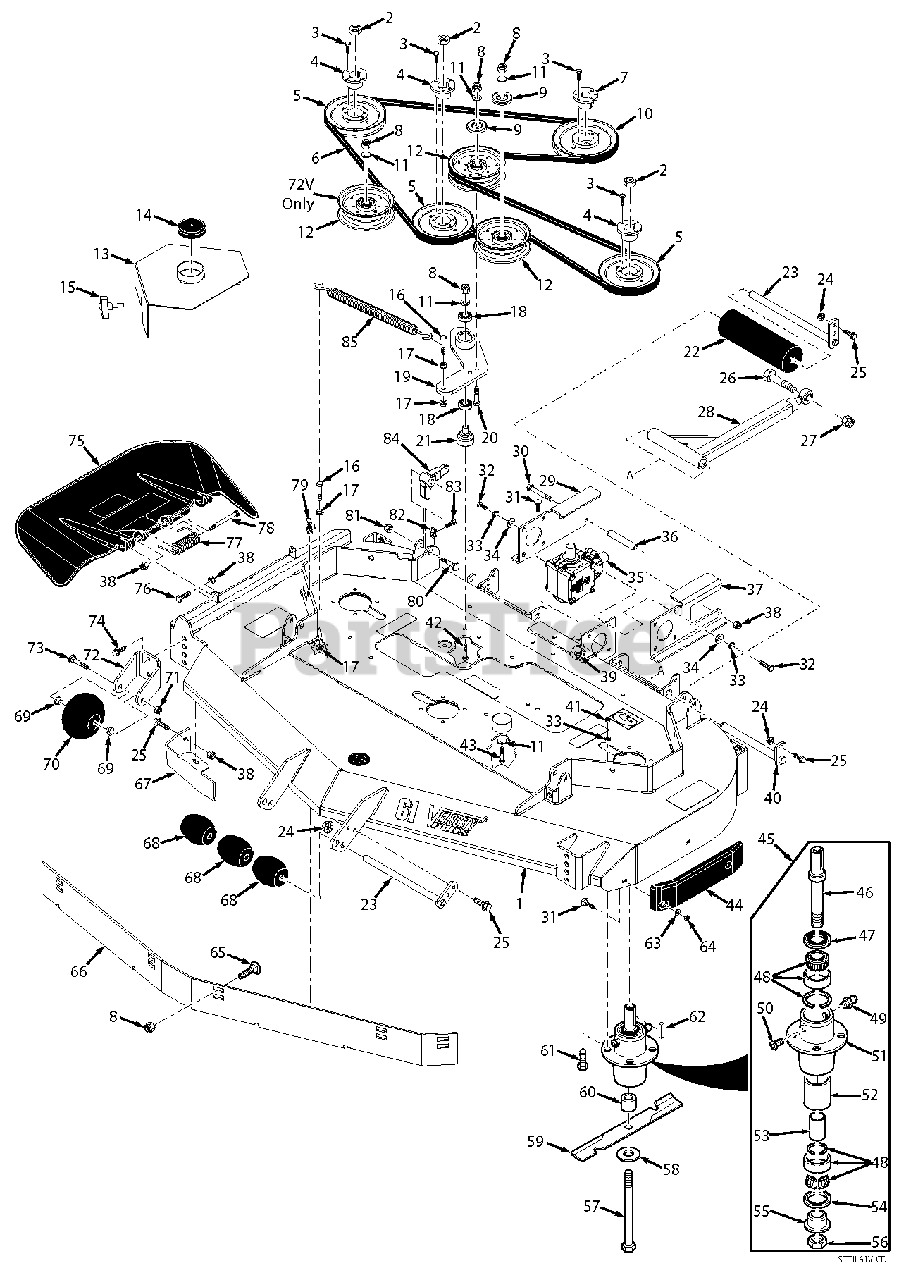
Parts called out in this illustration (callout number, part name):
1	Cutter Deck w/Decals - 72V
2	Nut, 5/8-11 UNC
3	Bolt, Hex Head 1/4-20 x 1"
4	Tapered Hub, 1-1/8" Bore
5	Pulley, 6.35 O.D.
5	Pulley, 6.95 O.D.
6	Belt, Deck Drive - 72V
7	Tapered Hub, 1" Bore
8	Nut, Elastic Stop 3/8-16
9	Dust Shield
10	Pulley, 6.75 O.D.
10	Pulley, 6.35 O.D.
10	Pulley, 5.75 O.D. (72V-25KBD)
11	Flatwasher, 3/8-.391 x .938 x .105 HD
12	Pulley, Idler
13	Belt Cover, LH 72V
13	Belt Cover, RH 72V
14	Cap, Spindle
15	Knob w/Stud
16	Bolt, Hex Head 3/8-16 x 1-1/2"
17	Nut, Serrated Flange 3/8-16
18	Bearing
19	Idler Arm Assy.
20	Bolt, Hex Head 3/8-16 x 2-3/4"
21	Pivot, Idler
22	Guide Roller
23	Roller Shaft
24	Nut, Serr. Flange 5/16-18
25	Bolt, Hex Head 5/16-18 x 1"
26	Bolt, Hex Head 5/8-11 x 4-1/2"
27	Nut, Elastic Stop 5/8-11
28	Pusharm Assy., LH & RH
29	Mounting Plate
30	Bolt, Hex Head 5/16-18 x 4-3/4"
31	Bolt, Carriage 5/16-18 x 3/4"
32	Bolt, Hex Head 5/16-18 x 1"
33	Lockwasher, 5/16"
34	Flatwasher, 5/16-.375 x .875 x .083
35	Gearbox
36	Spacer
37	Mounting Plate
38	Nut, Elastic Stop 5/16-18
39	Nut, Serr. Flange 5/16-18
40	Shaft Weldment, Pusharm
41	Nut, Elastic Stop 5/16-18
42	Bolt, Hex Head 3/8-16 x 3"
43	Bolt, Hex Head 3/8-16 x 3-3/4"
44	Pad, Deck Wear
45	Spindle Assembly
46	Shaft, Spindle
47	Seal, Top
48	Bearing Assembly
49	Grease Fitting
50	Relief Fitting, Tapered Spindle
51	Spindle Housing
52	Spacer, Outside
53	Spacer, Inside
54	Seal, Bottom
55	Spindle Bushing, Bottom
56	Nut, Special 1-1/16 - 18
57	Bolt, Hex Head 5/8-11 x 9-1/2
58	Flatwasher, 5/8-.688 x 1.75 x .134 HD
59	Cutter Blade, 24-1/2"
60	Spacer, Spindle Bottom
61	Bolt, Hex Head 5/16-18 x 1-3/4"
62	Key, 1/4 x 1/4 x 2"
63	Flatwasher, 5/16-.344 x .688 x .065
64	Nut, Center Lock 5/16-18
65	Bolt, Carriage 3/8-16 x 1"
66	Baffle, Custom Cut - 72V
67	Baffle, Turbo - 72V
67	Baffle, Turbo - 72V (CA)
68	Wheel, Anti-Scalp
69	Bushing, .376 I.D. Oilite
70	Anti-Scalp Wheel
71	Nut, Center Lock 3/8-16
72	Bracket, Anti-Scalp
73	Bolt, Carriage 3/8-16 x 4"
74	Bolt, Hex Head Serr. Flange 3/8-16 x 1"
75	Discharge Chute Assy.
75	Discharge Chute Assy. (CA)
76	Bolt, Hex Head 5/16-18 x 1-3/4"
77	Spring, Discharge Chute
78	Bolt, Hex Head 5/16-18 x 4-3/4"
79	U-Nut, 3/8-16
80	Bolt, Carriage 7/16-14 x 2-1/4"
81	Nut, Elastic Stop 7/16-14
82	U-Nut, 3/8-16 (short)
83	Bolt, Hex Head 3/8-16 x 2" Special
84	Lever, Deck Level
85	Spring
